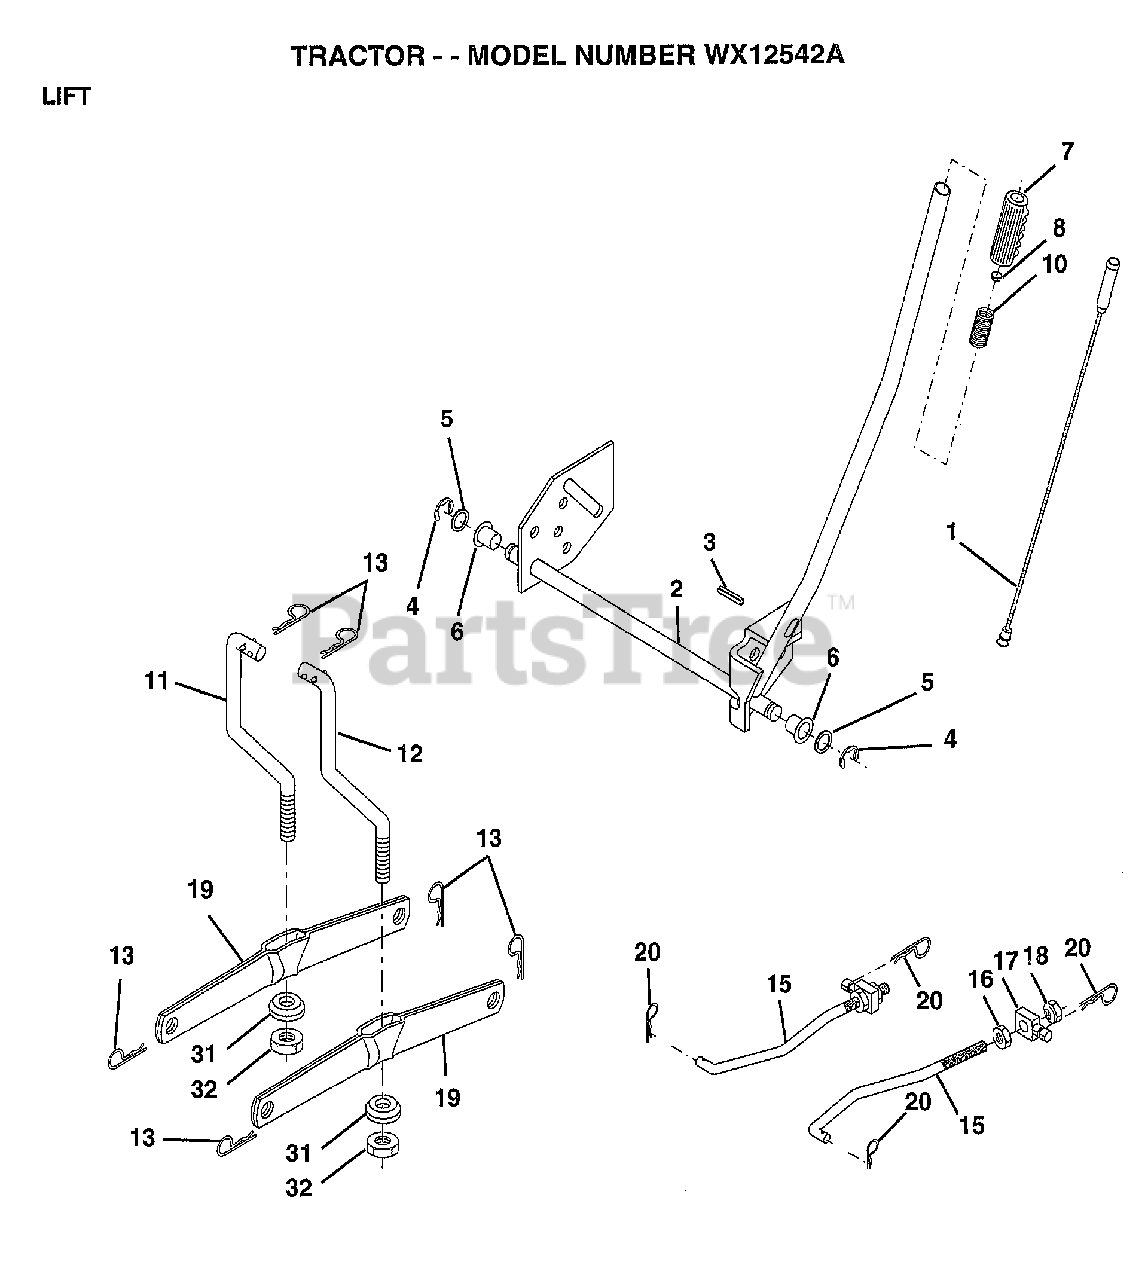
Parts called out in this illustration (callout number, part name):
1	WIRE ASM
3	PIN-GROOVE LT
5	WASHER
6	NYLON BEARING
7	GRIP
15	LINK.FRONT
16	NUT
17	TRUNION
18	NUT.LK.W/WSH.1/2.
19	ARM SUSP REAR
20	RETAINER.SPRING
31	BEARING PVT LH
32	NUT.CROWNLOCK.3/8
